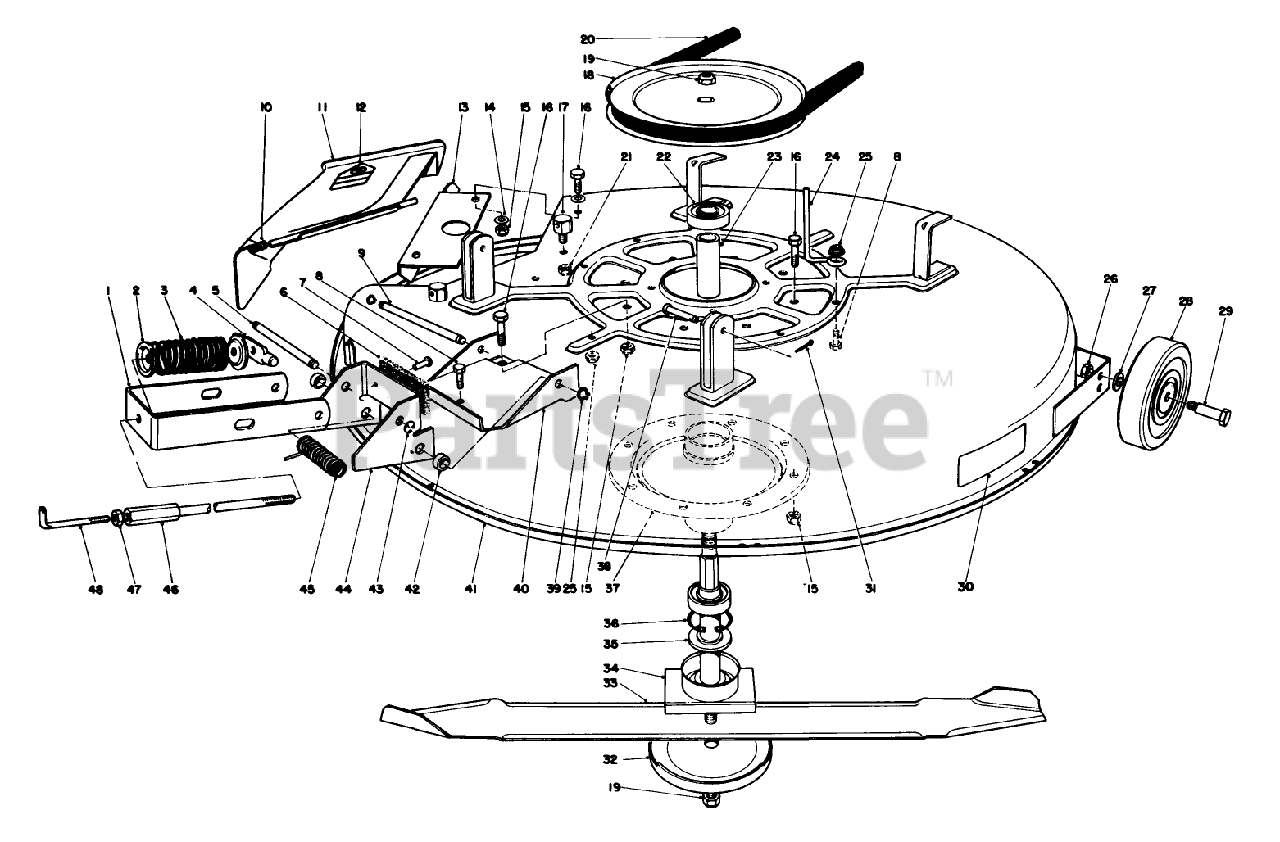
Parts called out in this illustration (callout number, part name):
2	RETAINER-SPR. TOP
3	SPRING-COMPRESSION
4	SHAFT-DECK ADJ.
6	BRAKE PAD
8	SCREW-HH
9	CLEVIS PIN
10	SPRING
11	DEFLECTOR ASM
14	WASHER-PLAIN
15	NUT-LOCK, NI
16	SCREW-HH
17	POST-PIVOT
18	PULLEY
19	NUT-SPECIAL
20	V-BELT, DECK
21	NUT-LOCK, SIDE
22	BEARING-BALL
24	BELT GUIDE
25	NUT-LOCK, HHF
27	WASHER-FLAT
31	PIN-COTTER
34	SPINDLE SHAFT WA
35	SPACER-SPINDLE
38	PIN-CLEVIS
39	RING-RETAINING
43	E-RING
45	SPRING
47	NUT-JAM
